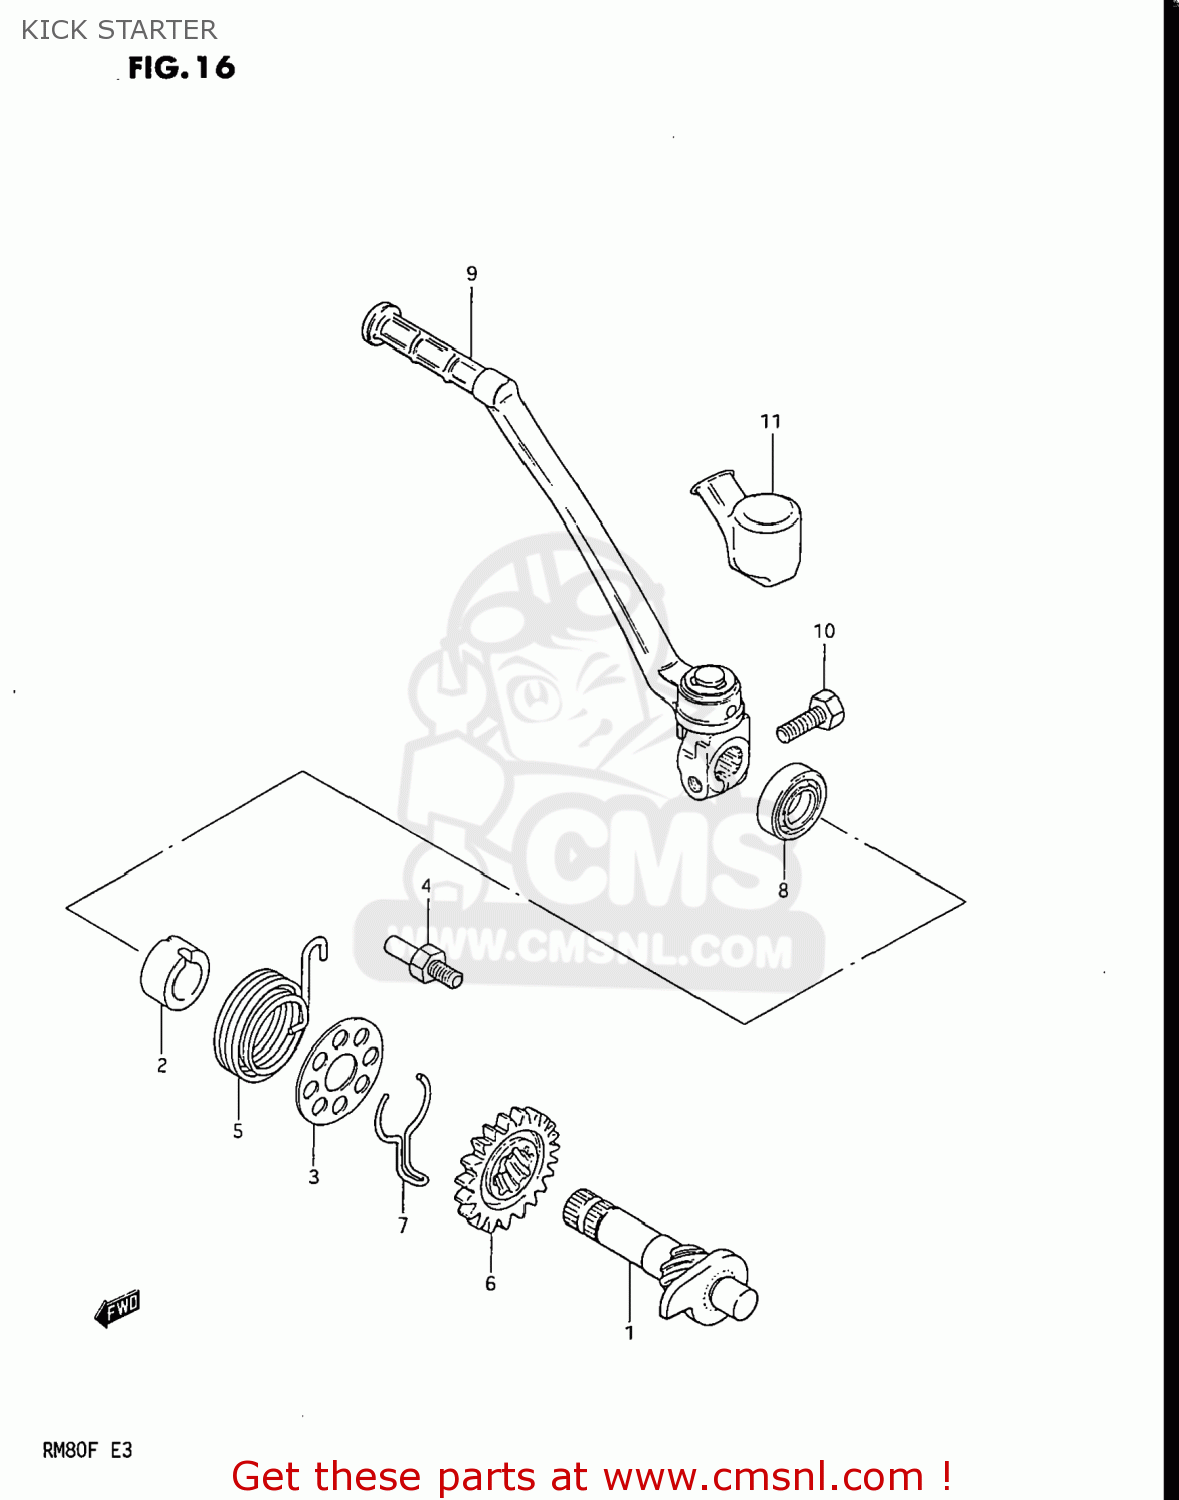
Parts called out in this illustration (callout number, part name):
1	SHAFT,KICK STARTER
2	GUIDE,KICK STARTER SFT SPRING
3	HOLDER,KICK STARTER SHAFT SPR
4	BOLT,KICK START SHAFT SPR HOOK
5	SPRING
6	GEAR,KICK STARTER DRIVE
7	SPRING,RETAINER
8	SEAL,OIL(14X24X6)
9	LEVER ASSEMBLY,KICK STARTER
10	BOLT
11	COVER,KICK LEVER JOINT
